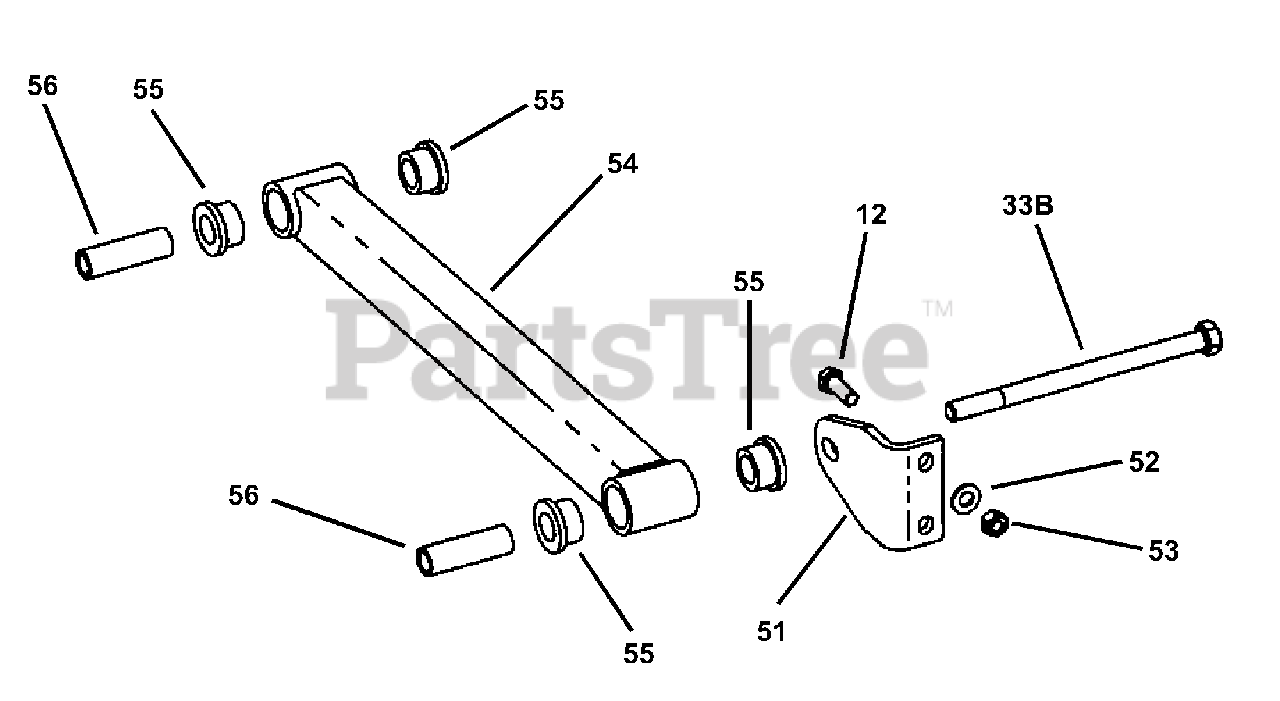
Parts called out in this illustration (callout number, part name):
12	BOLT, 3/8-16 X 1" GD5 CZ
33B	BOLT, 1/2-13 X 7-1/2" GD5 YZ
51	L-BRK'T, Deck Stabilizer Bar
52	WASHER, 3/8" Flat
53	NUT, 3/8-16 Hex Center Lock
54	STRUCTURE, 52" Stabilizer Bar
55	BUSHING, Suspension
56	SLEEVE, Suspension
